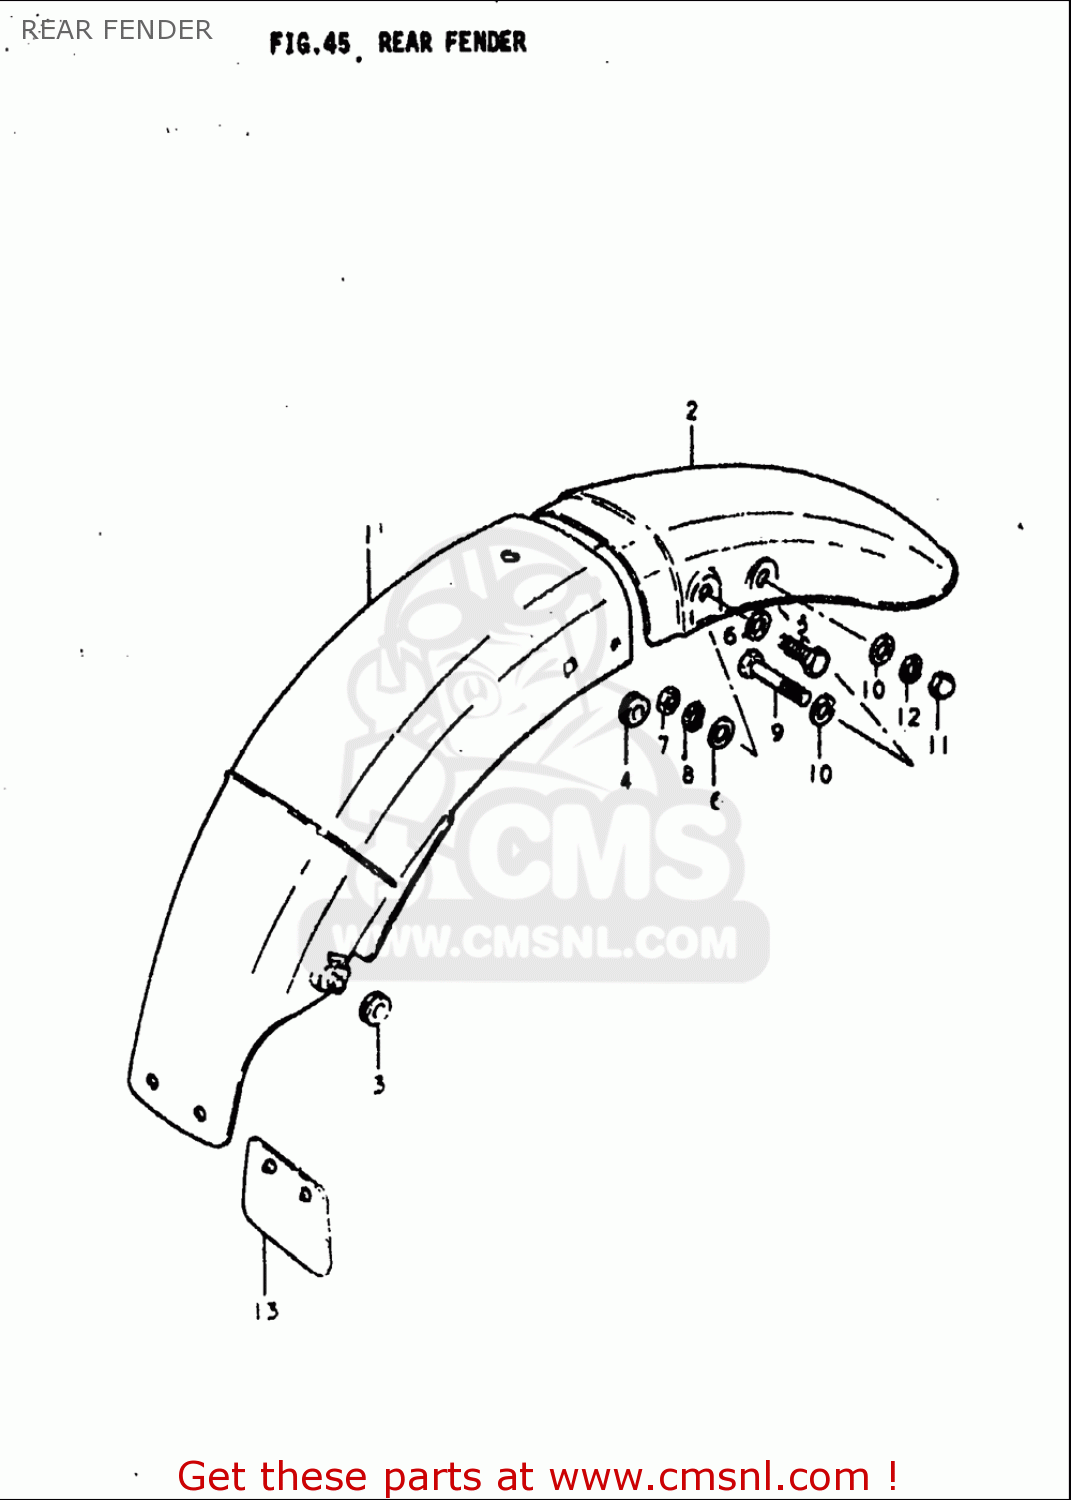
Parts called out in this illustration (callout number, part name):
3	CUSHION
4	CUSHION
5	BOLT
6	WASHER
7	NUT
8	WASHER,LOCK
9	BOLT
10	WASHER
11	NUT
12	WASHER,LOCK
13	GUIDE,RR FENDER MUD
